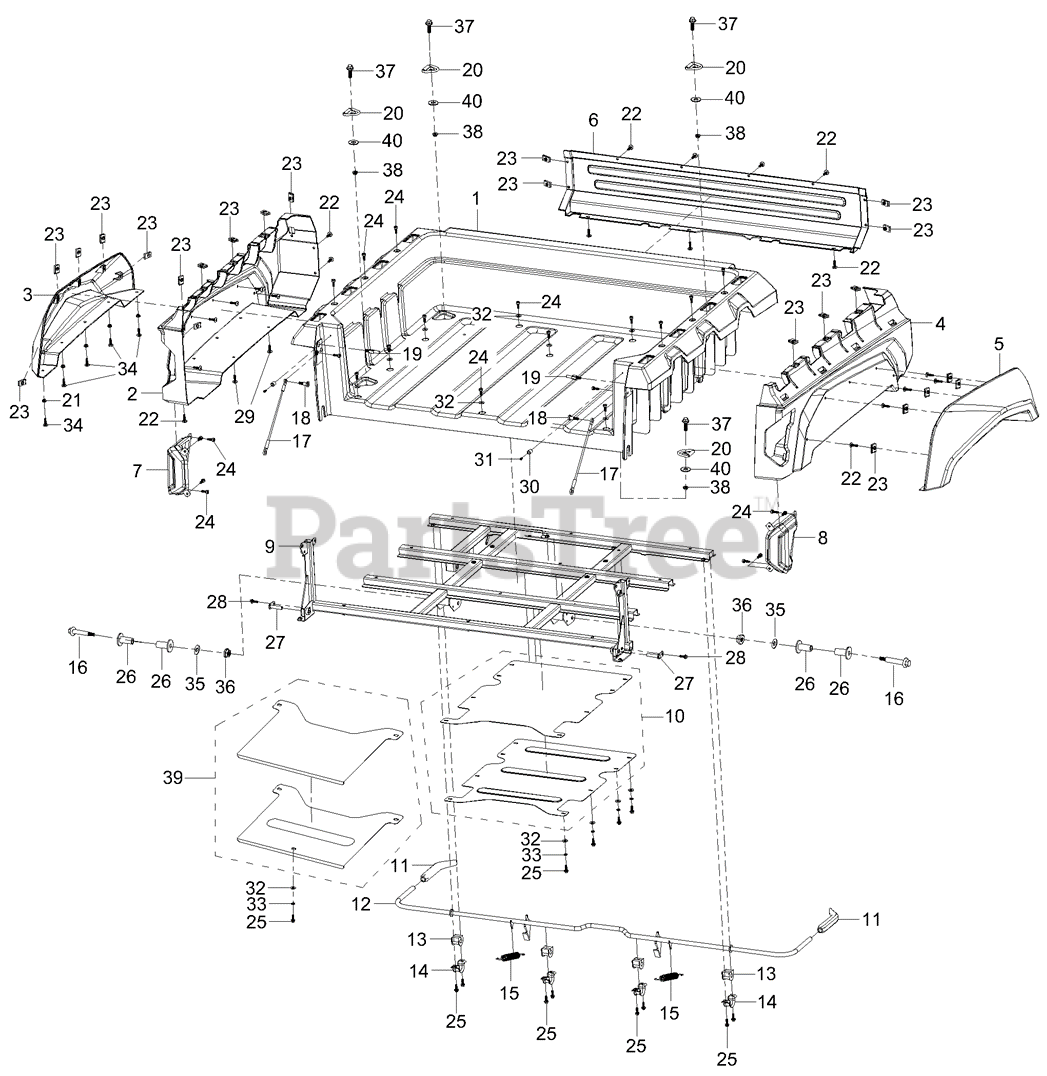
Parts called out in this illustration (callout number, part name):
1	CARGO BED
2	CARGO BED SIDE PANEL LEFT RED
2	CARGO BED SIDE PANEL LH YELLOW
2	CARGO BED SIDE PANEL LEFT BLUE
2	CARGO BED SIDE PANEL LH BLACK
2	CARGO BED SIDE PANEL LEFT CAMO
3	FENDER - REAR LEFT TOP
4	CARGO BED SIDE PANEL RIGHT RED
4	CARGO BED SIDE PANEL RH YELLOW
4	CARGO BED SIDE PANEL RH BLUE
4	CARGO BED SIDE PANEL RH BLACK
4	CARGO BED SIDE PANEL RH CAMO
5	FENDER - REAR RIGHT TOP
6	FRONT CARGO BED PANEL
7	TAIL BRAKE LIGHT ASM REAR LEFT
8	TAIL BRAKE LIGHT ASM REAR RIGHT
9	CARGO BED FRAME
10	HEAT PROTECTOR - CARGO BED
11	RELEASE LEVER GRIP
12	CARGO BED RELEASE LEVER KIT
13	RELEASE LEVER CUSHION
15	TENSION SPRING 2X14X40
16	PIN CARGO BED KIT
17	CABLE - CARGO BED DOOR
18	SHOULDER BOLT M8X15-10X14.5
19	SHOULDER BOLT M8X15-10X10-53
20	CARGO BED HOOK
21	HEX FLANG NUT M6
22	SCREW M6X16
23	CLAMP NUT M6X6
24	SOCKET HEX FLAT HEAD BOLT M6X16
25	HEXAGON FLANGE BOLT M6X16
26	BUSHING - PLASTIC 12X18
27	HINGE STRAP
28	HEX HEAD FLANGE BOLT M8X12
29	SCREW - CROSS HEAD SELF TAPPING
30	CARGO DOOR SHOCK ABSORBER
31	SCREW - CROSS HEAD SELF TAPPING
32	FLAT WASHER
33	SPRING WASHER
34	HEX HEAD CAP SCREW M6X16
36	LOCK NUT M8
37	HEX FLANGE BOLT M10-1.50X30
38	LOCK NUT M10X1.25
39	INSULATION PLATE II
40	WASHER - FLAT 10X28X2
